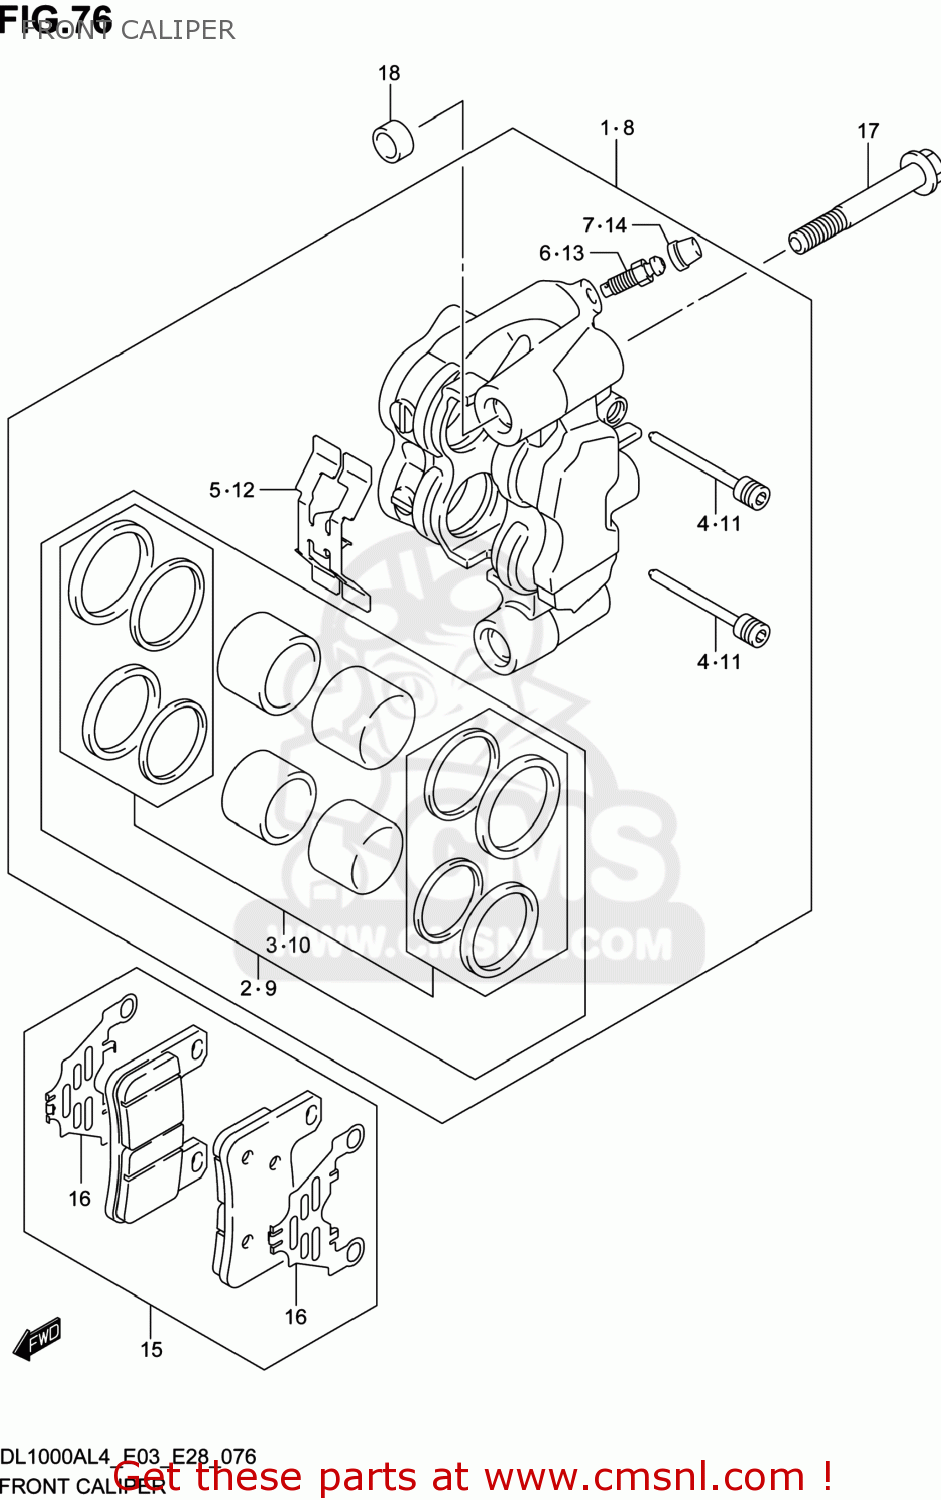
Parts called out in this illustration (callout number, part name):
1	CALIPER ASSY,FR,R
2	PISTON SET
3	SEAL SET,PISTON
4	PIN
5	SPRING,PAD
6	BLEEDER
7	CAP,BLEEDER PLUG
8	CALIPWE ASSY,FR,L
9	PISTON SET
10	SEAL SET,PISTON
11	PIN
12	SPRING,PAD
13	BLEEDER
14	CAP,BLEEDER PLUG
15	PAD SET (NAS)
16	SHIM
17	BOLT(10X70)
18	PIN,CALIPER
